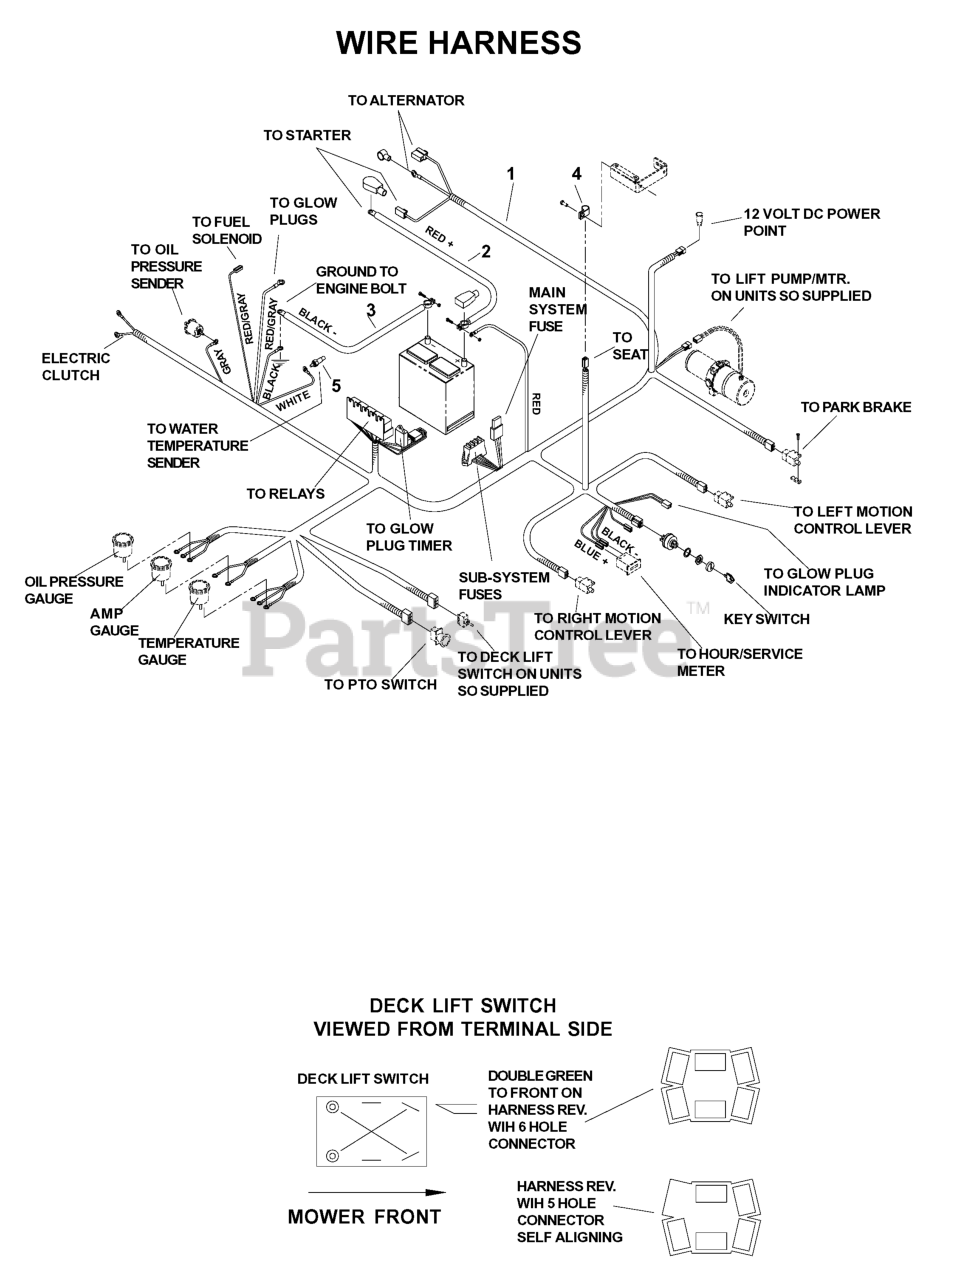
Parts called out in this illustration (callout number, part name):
1	HARNESS, ENG - B&SD DIESEL
2	CABLE, POS.
3	CABLE, NEG.
5	SENDER,TEMP
